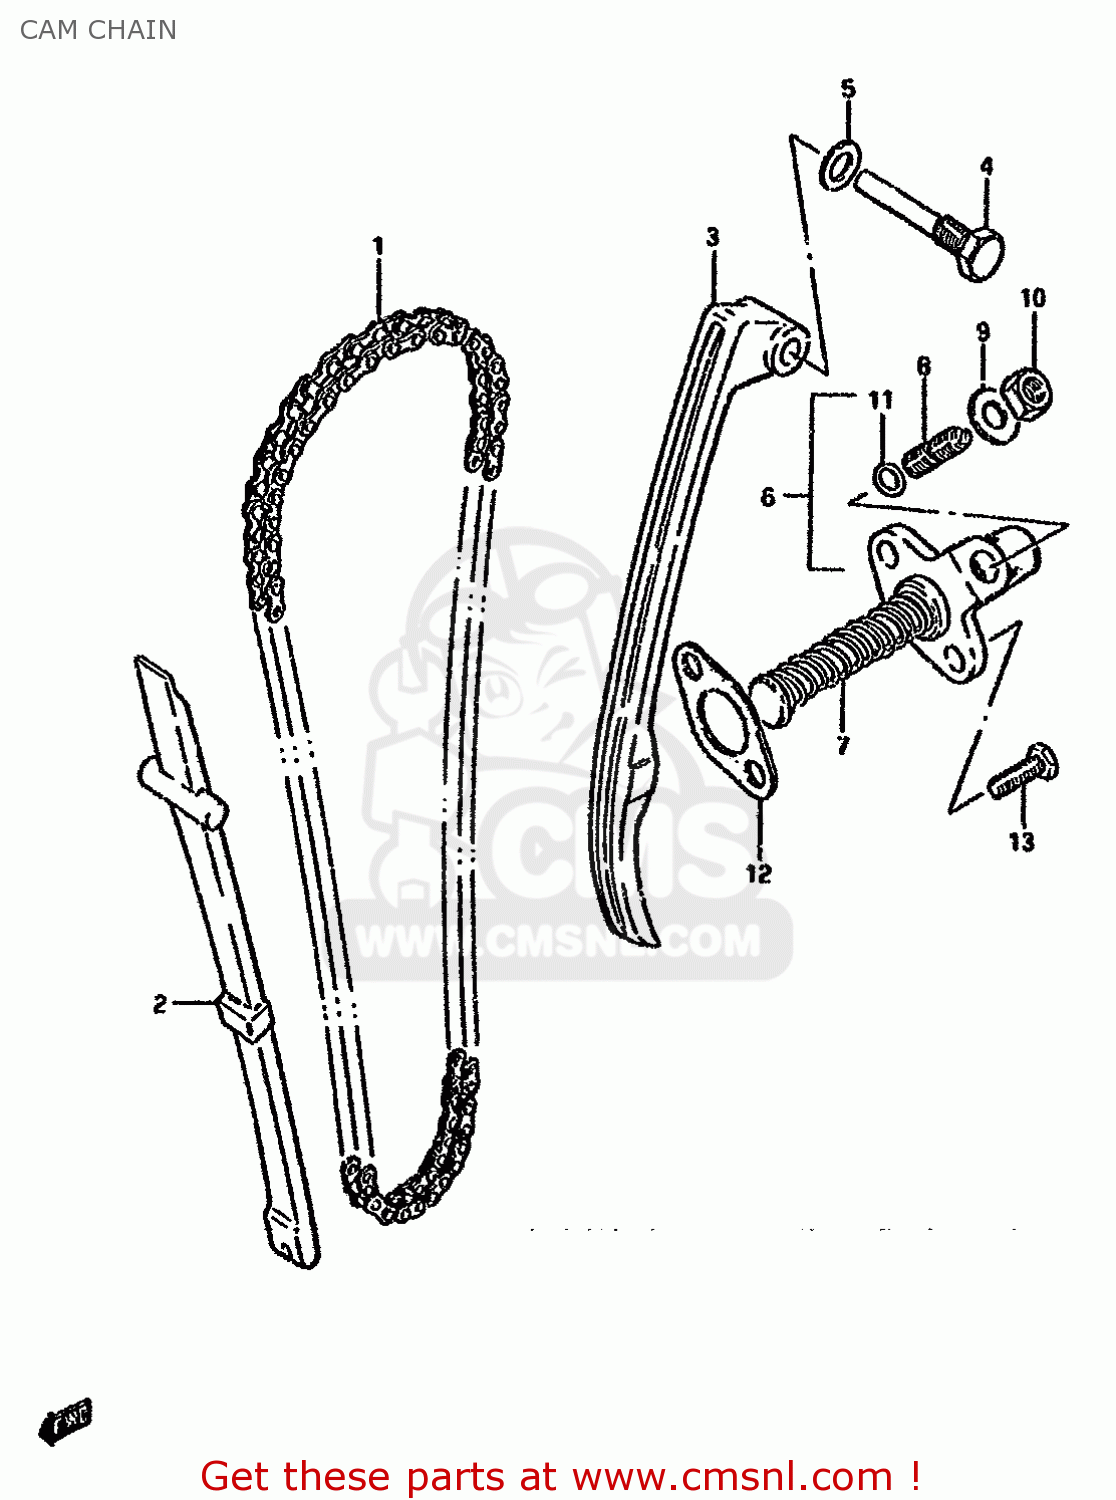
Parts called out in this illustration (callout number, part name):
1	CHAIN,CAMSHAFT DRIVE
2	GUIDE,CAM CHAIN
3	TENSIONER,CAM CHAIN
4	BOLT,CAM CHAIN TENSIONER
5	GASKET 8.2X14X1 (NAS)
6	ADJUSTER ASSY,TENSIONER
7	SPRING
8	SCREW
9	WASHER
10	NUT
11	O RING(D:1.9,ID:5.7)
12	GASKET,TENSIONER ADJUSTER (NAS)
13	BOLT
